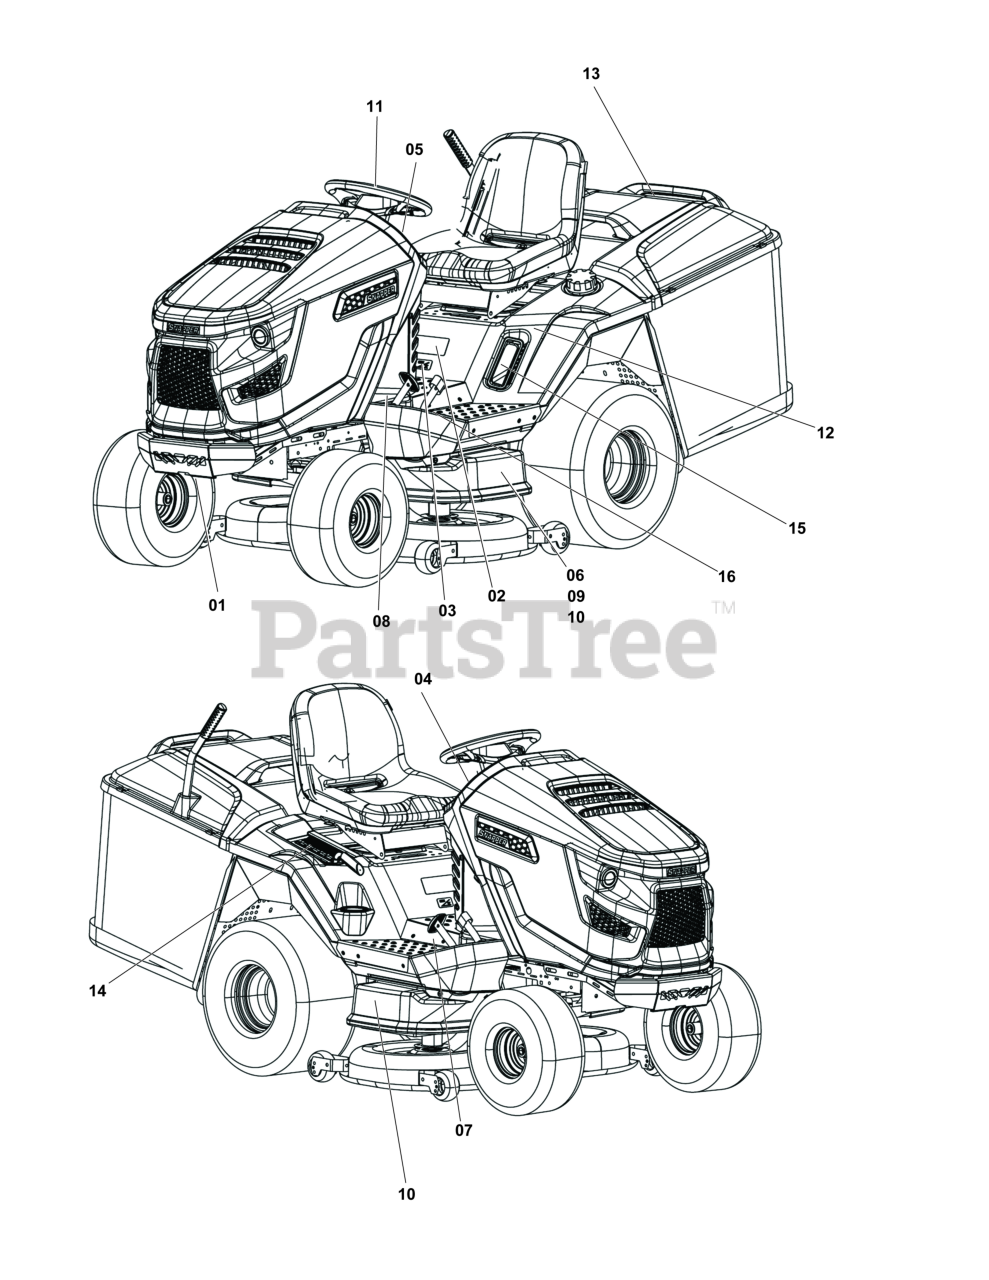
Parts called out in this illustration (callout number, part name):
04	DECAL, DASH, LH, RTX
05	DECAL, DASH, RH, RTX
09	DECAL, Noise
11	DECAL, Brand
12	DECAL, Model
13	DECAL, Brand
14	DECAL, Cutting Height
